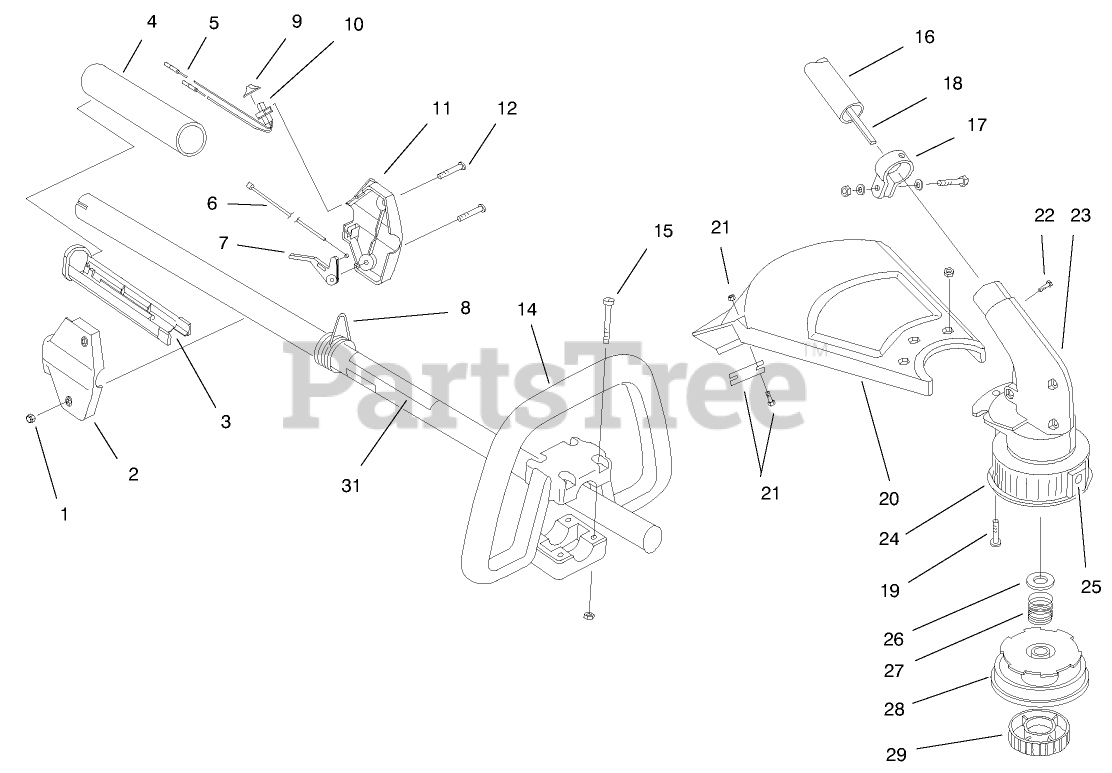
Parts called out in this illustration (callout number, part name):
1	NUT-LOCK, NI
2	RH HOUSING
3	TROUGH 1"
4	GRIP - RUBBER
9	SWITCH COVER
10	SWITCH
11	LH HOUSING
15	HARDWARE - HANDLE
17	CLAMP ASM - UPPER
19	ASM - GUARD MTG SCREW
21	BLADE ASM
22	ANTI-ROTATION SCREW
24	OUTER SPOOL EYELET ASM
25	EYELET
26	RETAINER WASHER
27	SPRING
28	REEL - INNER
